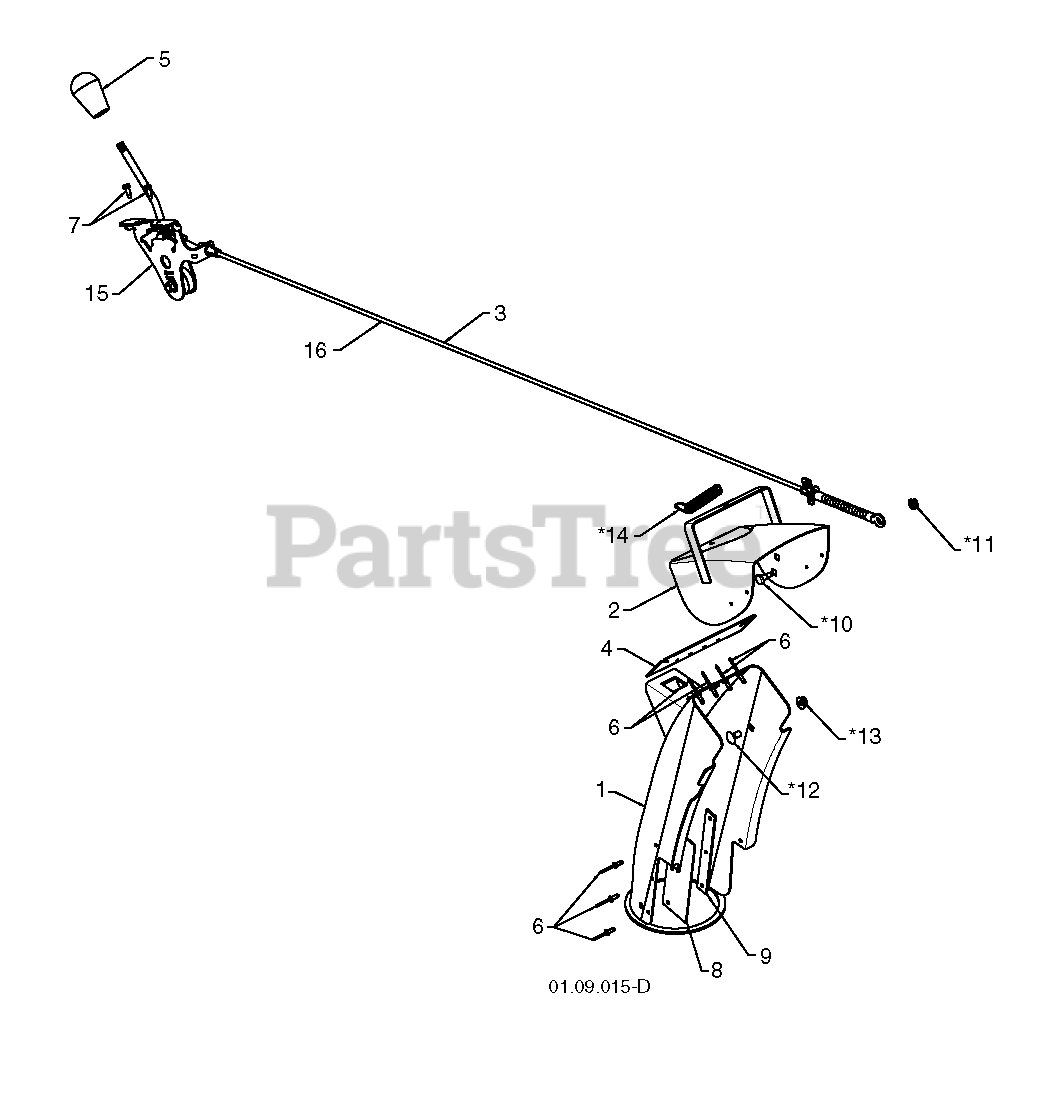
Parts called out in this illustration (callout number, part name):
3	Deflector Control Cable Assembly, Black
4	SEAL.DEFLECTOR
5	KNOB LEVER, BLACK
6	RIVET BLIND
7	SCREW
8	SHIELD.SNOW.CHUTE
9	STRAP.SHEILD.RETAINER
10	BOLT, SHOULDER
11	NUT.HEX.FLANGE.1/4
12	BOLT
13	NUT, LOCK 5/16-18
15	CHUTE.DEFLECTOR.HEAD.SERVICE.
16	Deflector Cable, Snow
